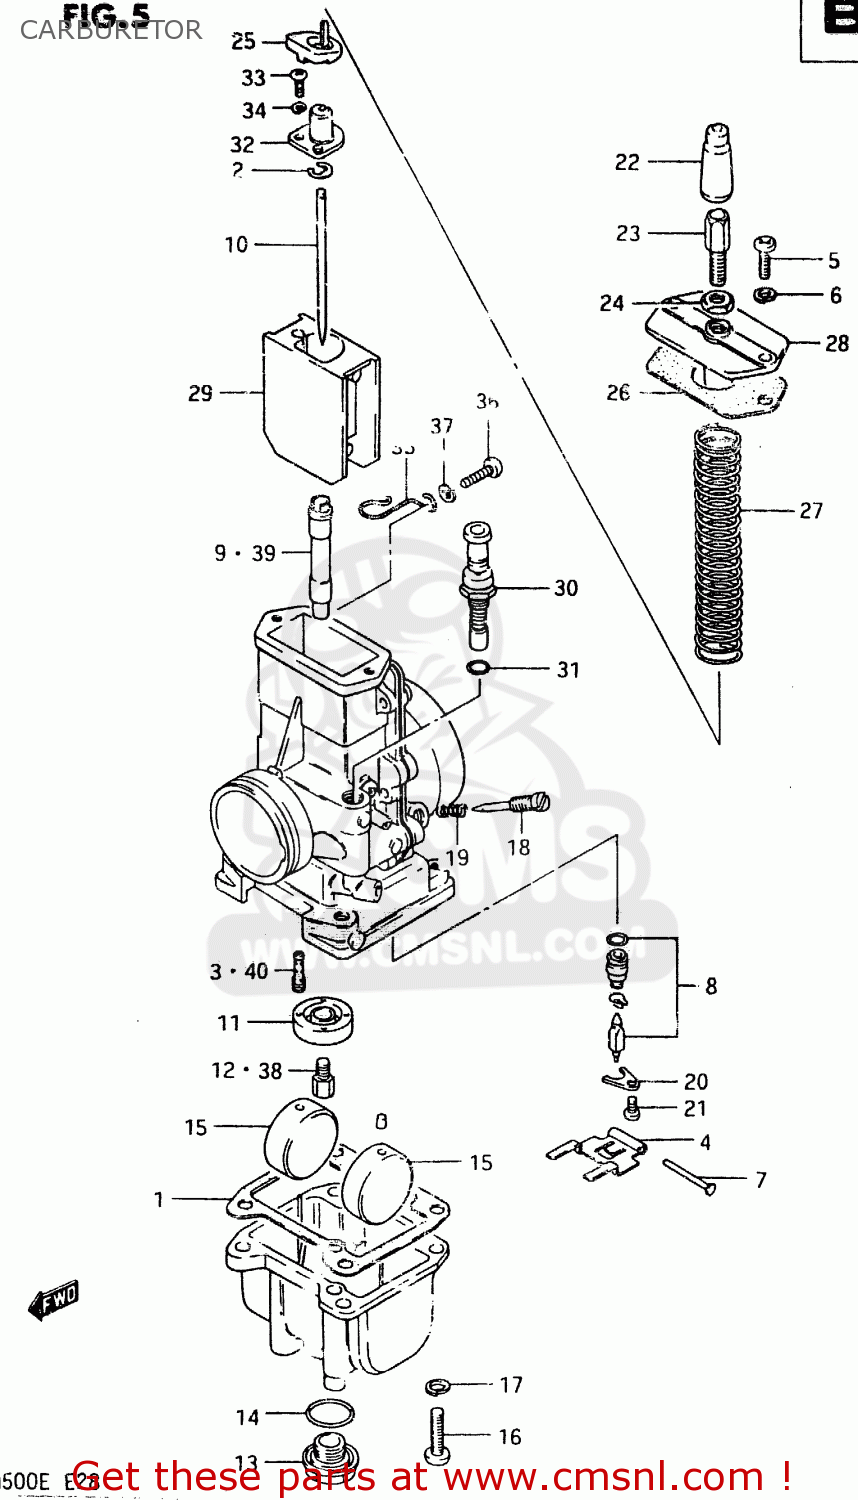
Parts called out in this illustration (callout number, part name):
1	GASKET,FLOAT CAHMBER (NAS)
2	CLIP
3	JET,PILOT(50)
4	ARM,FLOAT
5	SCREW
6	LOCK WASHER
7	PIN,FLOAT
8	VALVE ASSEMBLY,NEEDLE
9	JET,NEEDLE
10	NEEDLE JET
11	RING,MAIN JET FIXING
12	JET,MAIN(300)
13	SCREW,GUIDE
14	O RING,DRAIN PLUG
15	FLOAT
16	SCREW 5X20
17	LOCK WASHER
18	SCREW,PILOT AIR
19	SPRING
20	PLATE
21	SCREW 4X6
22	CAP,CABLE ADJUSTER
23	ADJUSTER,CABLE
24	NUT
25	SEAT,RETURN SPRING
26	GASKET,MIXING CHAMBER (NAS)
27	SPRING,THROTTLE VALVE
28	CAP,CARBURETOR,TOP
29	VALVE,THROTTLE
30	VALVE,STARTER
31	O-RING
32	PLATE,NEEDLE JET
33	SCREW
34	LOCK WASHER
35	CLIP
36	SCREW
37	LOCK WASHER
38	JET
39	JET,NEEDLE
40	JET
